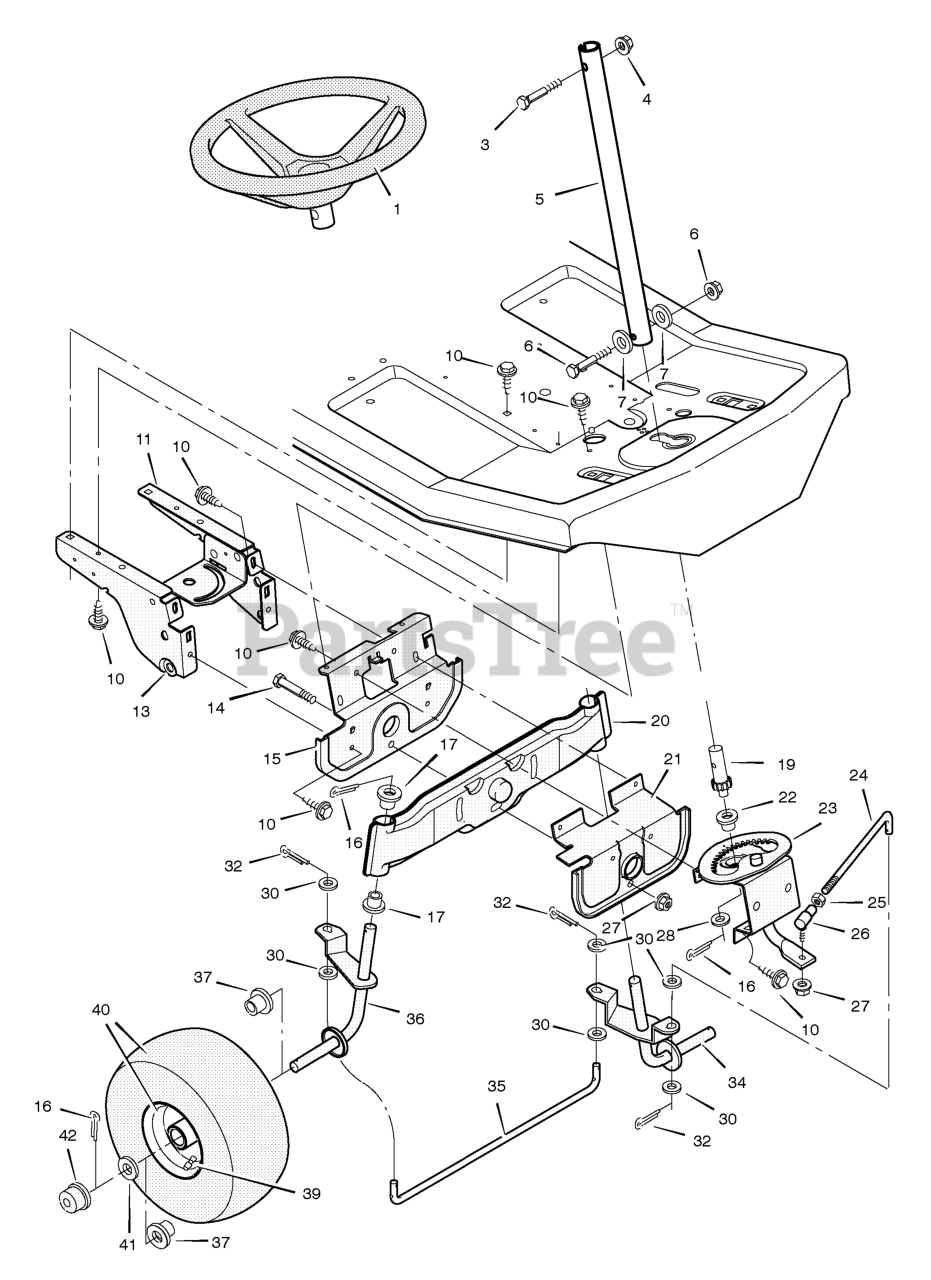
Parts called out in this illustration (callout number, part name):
1	Steering Wheel
3	Bolt, Hex
4	Locknut, Flange
5	Post, Steering
6	Nut, Hex
7	Washer
11	Plate, Left Suspension
13	Plate, Right Suspension
14	Bolt, Hex
15	Support, Front Axle
16	Pin, Cotter
17	Bearing, Spindle
19	Gear, Pinion
20	Axle Assembly, Front
21	Hanger Assembly, Front Axle
22	Bearing
23	Sector Assembly
24	Rod, Drag Link
25	Ball Joint, Steering
26	Nut, Hex
27	Locknut, Flange
28	Washer
30	Washer
32	Pin, Cotter
34	Spindle Assembly, Left
35	Rod, Tie
36	Spindle Assembly, Right
37	Bearing, Wheel
39	Valve Stem
40	Wheel & Tire Assembly
42	Cap, Hub
